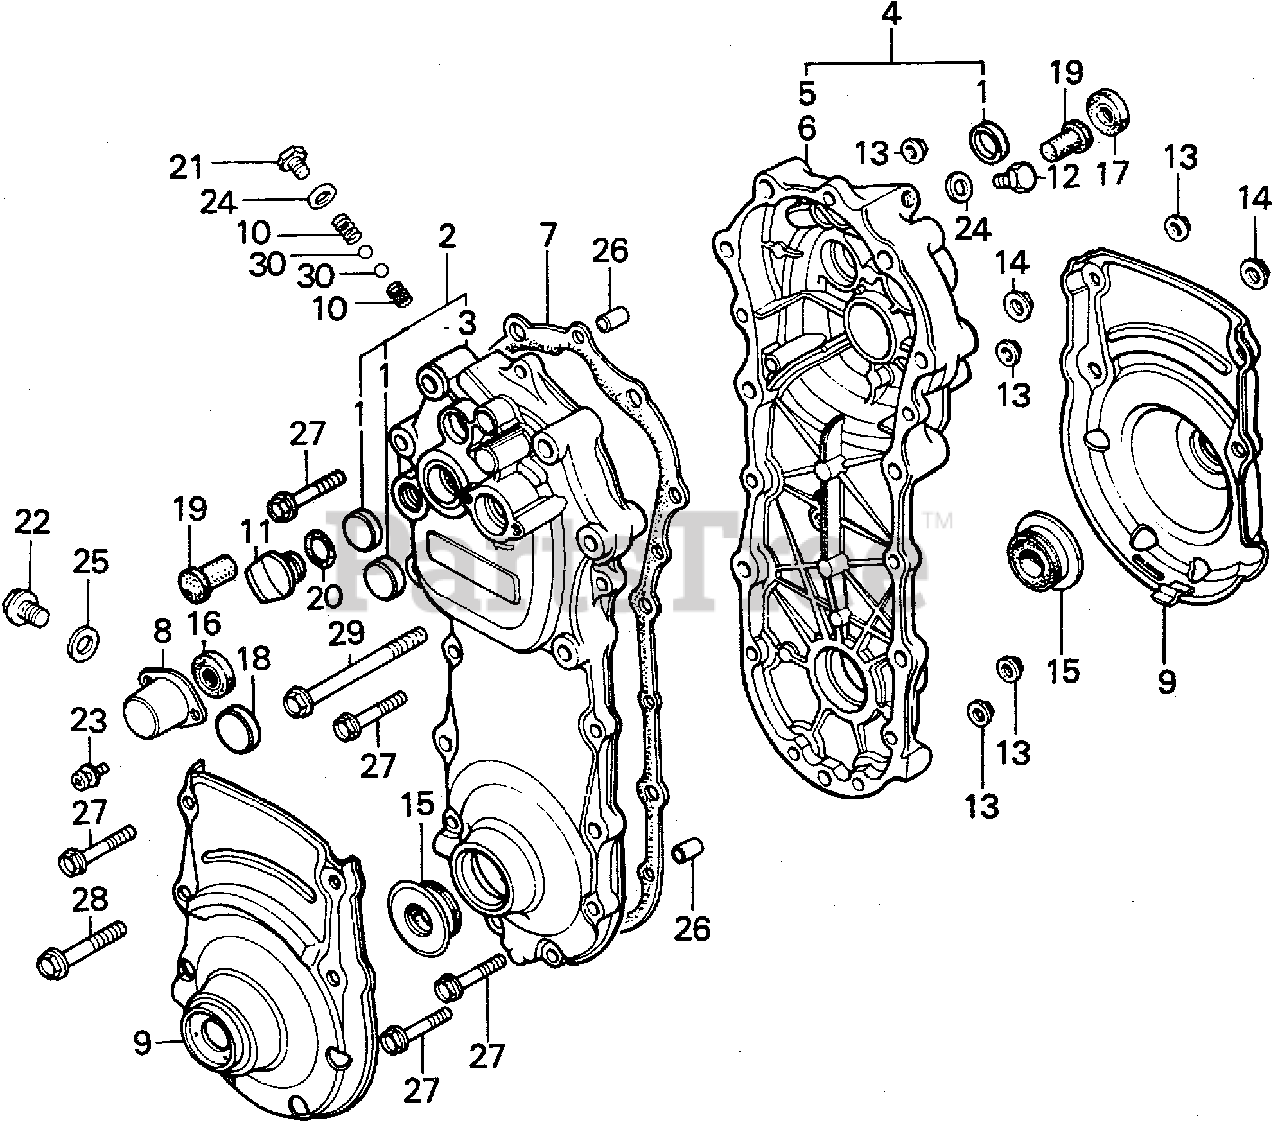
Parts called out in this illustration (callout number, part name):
1	PLUG, SEALING (30MM)
2	CASE ASSY., R. TRANSMISSION
3	CASE, R. TRANSMISSION (NOT AVAILABLE)
4	CASE ASSY., L. TRANSMISSION (NOT AVAILABLE)
5	CASE, L. TRANSMISSION
6	CASE, L. TRANSMISSION
7	GASKET, TRANSMISSION CASE (NOT AVAILABLE)
7	GASKET, TRANSMISSION CASE
9	PROTECTOR, CASE
9	PROTECTOR, CASE (NOT AVAILABLE)
12	BOLT, HEX. (8X10)
13	NUT, FLANGE (6MM)
14	NUT, FLANGE (8MM)
15	SEAL, WATER (48X32X19)
15	SEAL, WATER
16	OIL SEAL (17X30X8)
17	OIL SEAL (15X30X7)
18	PLUG, SEAL (22X7)
19	PLUG, BLIND (12MM)
20	O-RING (16MM)
21	BOLT, HEX. (8X10)
22	BOLT, DRAIN PLUG (12MM)
24	WASHER, PLAIN (8MM)
25	WASHER, DRAIN PLUG (12MM)
26	PIN, DOWEL (8X14)
27	BOLT, FLANGE (6X35)
28	BOLT, FLANGE (8X40)
29	BOLT, FLANGE (8X80)
